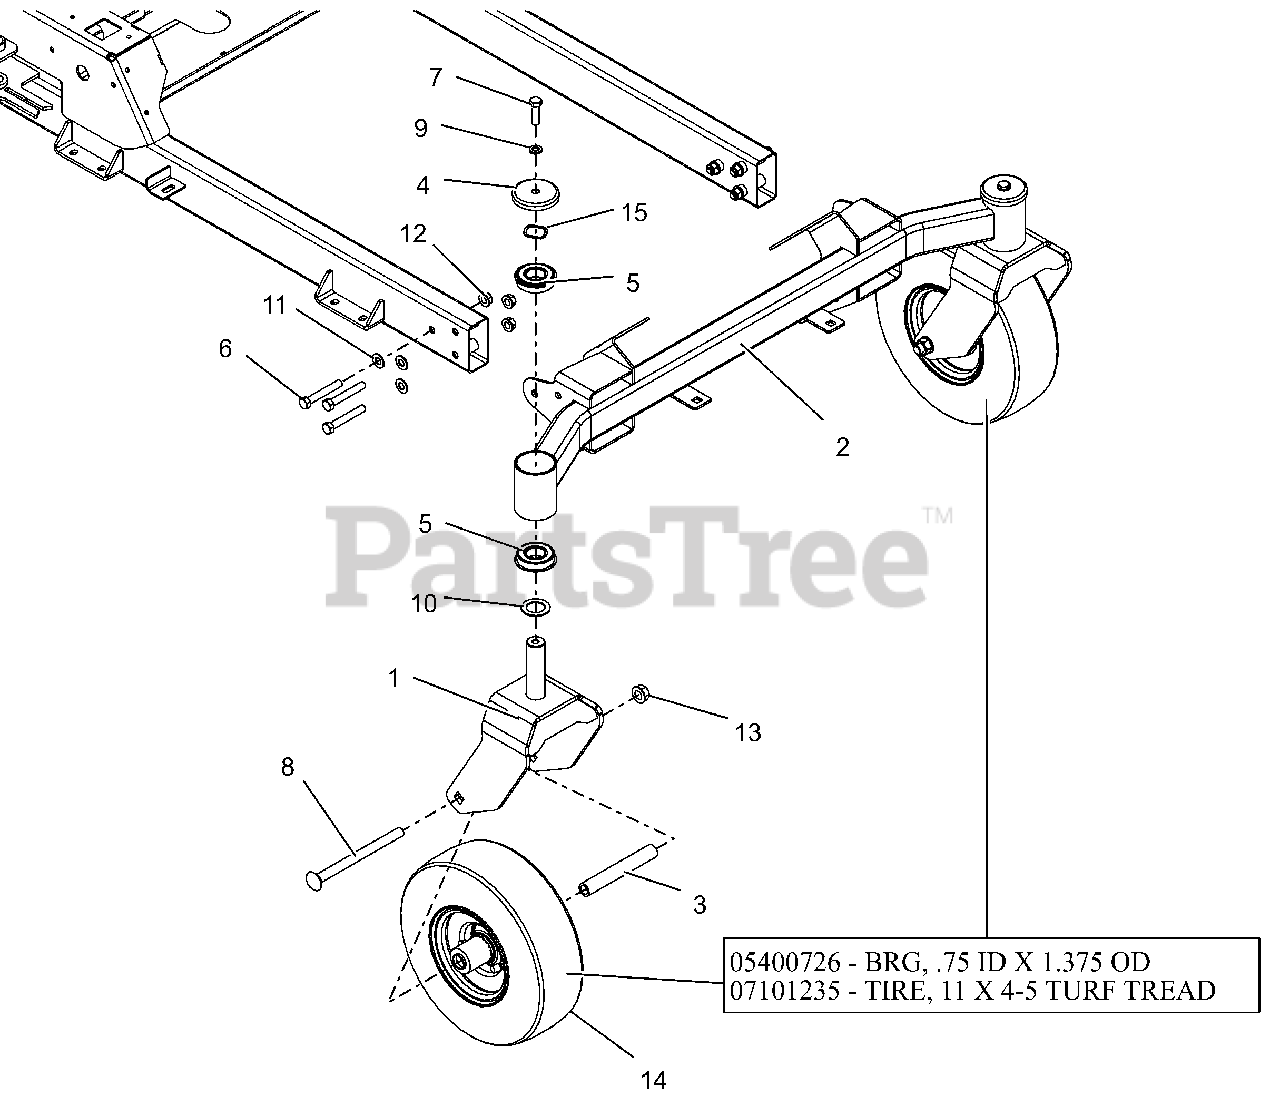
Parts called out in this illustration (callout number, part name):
1	WLDMT, CASTER FORK-X (RED)
2	WLDMT, FRONT AXLE-X/XL (RED)
3	SPACER, ROLLED WHEEL
4	SHIELD, AXLE BEARING
5	BEARING, BALL -2.000 OD X 1.000 ID X .5625 W/RING
6	BLT, HEX .38-16X2.50 G8 ZCC
7	BLT, HEX .38-16X1.25 G5 ZCC
8	BLT, RHSN .50-13X6.50 G5 ZCC
9	WSHR,LK-REG .375X.094 ZCC
10	WSHR-HRD-THRS 1.007X1.542X.062
11	WSHR-FL-STL 0.406X0.812X0.055 HRD
12	NUT-LK-TOP-FLG .375-16 GG ZCC
13	NUT-LK-TOP-FLG .500-13 GF ZCC
14	ASM, WHL/TIRE 11X4.00-5
14	BRG, .75 ID X 1.375 OD
14	TIRE, 11X4-5 TURF TREAD
15	WSHR-WAVE 1.0X1.25X.028 .145FH
